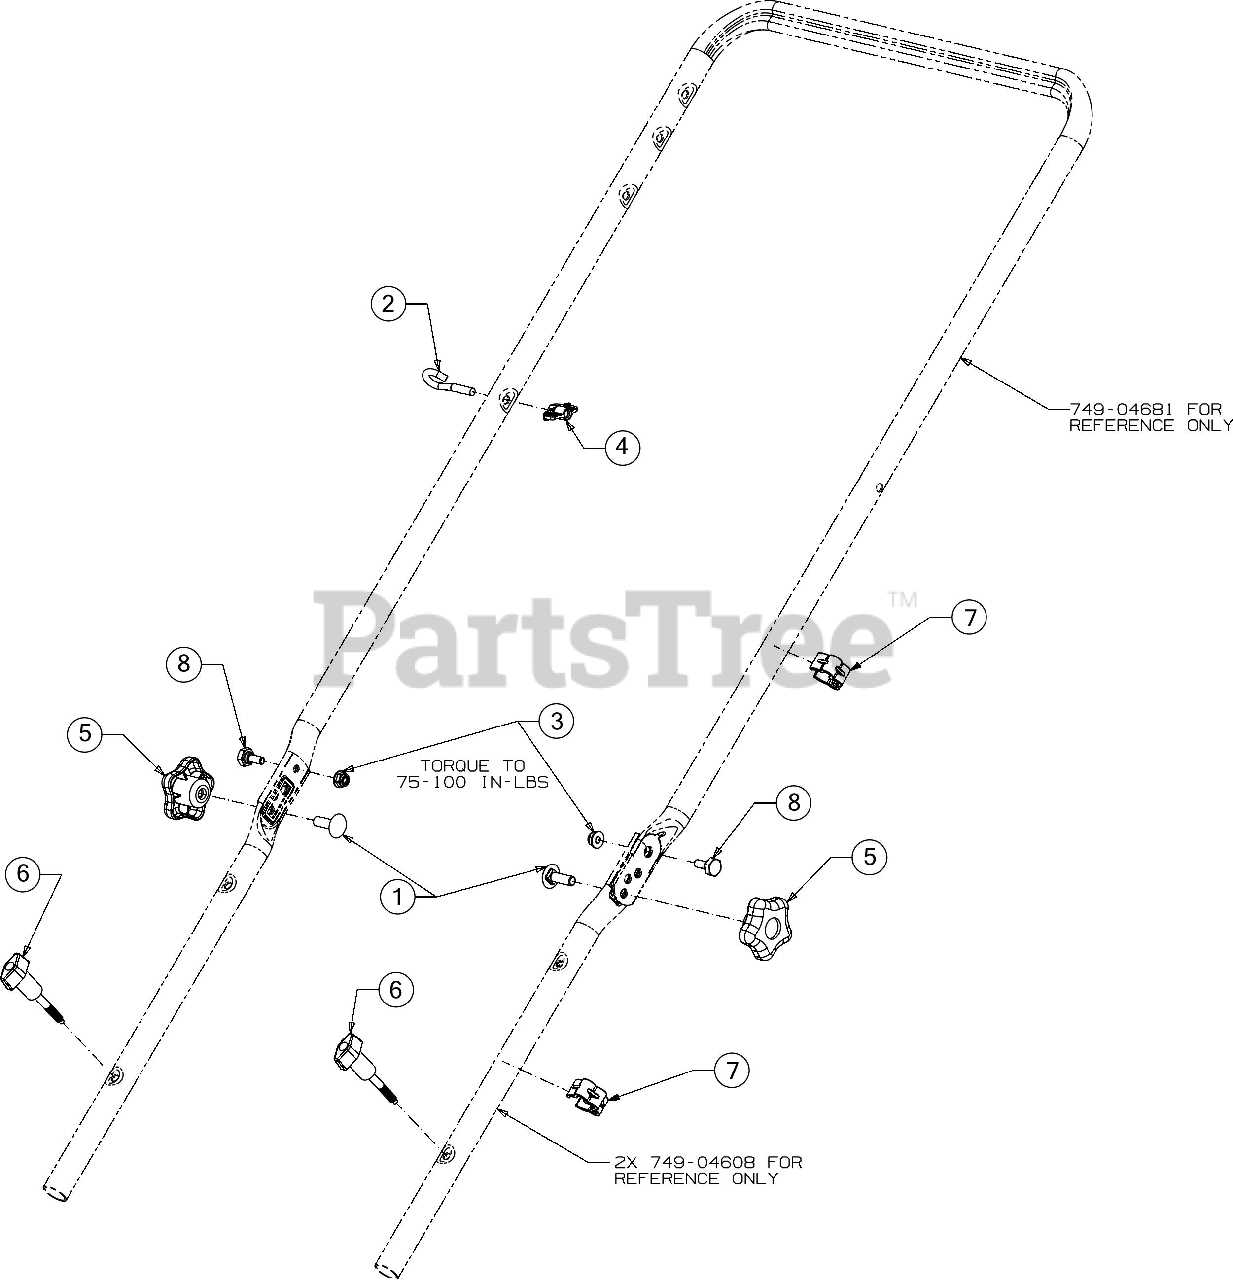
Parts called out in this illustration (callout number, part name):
1	SCREW 5/16-18 X 1.00 GR5
2	EYEBOLT 1/4-20
3	FLANGE LOCK NUT
4	HANDLE KNOB
5	STAR KNOB- RED
6	WING KNOB 1/4-20
7	CONDUIT CLIP
8	SHOULDER SCREW
